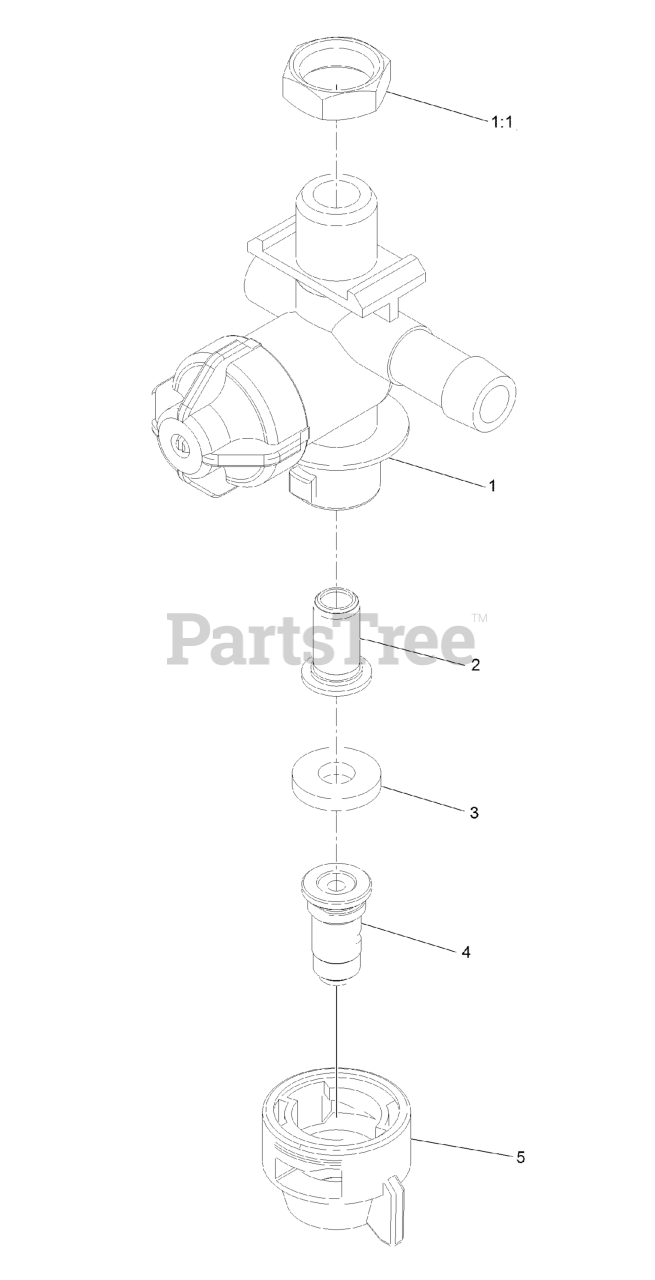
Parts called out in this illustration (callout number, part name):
1	LH NOZZLE BODY ASM
1:1	NUT-NYLON
2	STRAINER-TIP
4	NOZZLE-SPRAY, WHITE
5	CAP-NOZZLE
